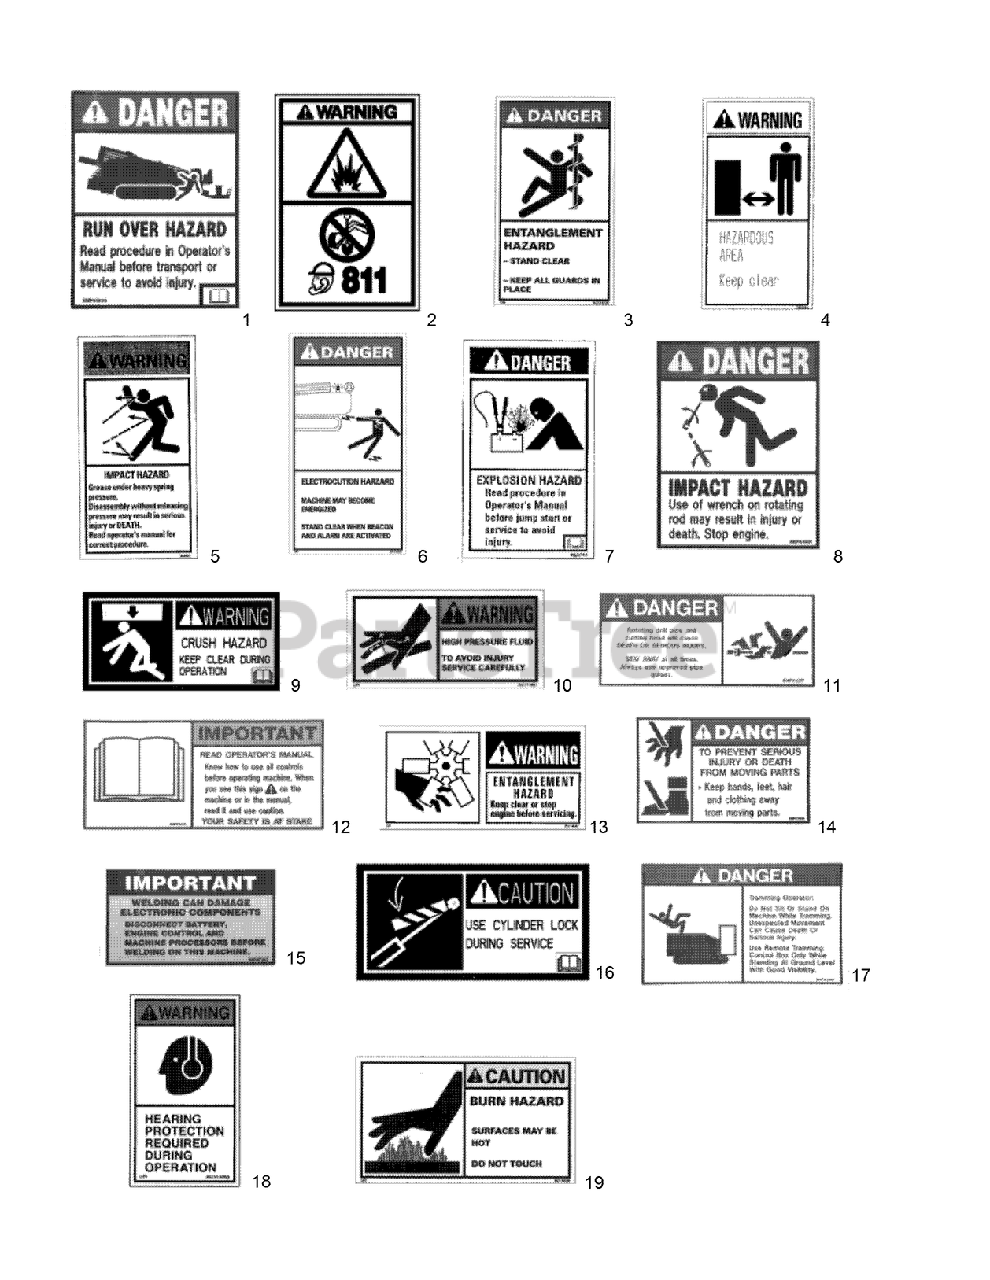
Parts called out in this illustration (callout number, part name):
1	DECAL - Danger, Run Over Hazard
2	DECAL-Warning, Call Before Digging
3	DECAL - Danger, Entanglement Hazard
4	DECAL - Warning, Hazardous Area
5	DECAL - Warning, Grease Under Pressure
6	DECAL - Danger, Electrocution
7	DECAL - Danger, Explosion Hazard
8	DECAL - Danger, Impact Hazard
9	DECAL - Warning, Crush Hazard
10	DECAL - Danger, Hydraulic Components Contain High Pressure Fluid
11	DECAL - Danger, Rotating Drill and Cutting Head
12	DECAL - Important, Read Operators Manual
13	DECAL - Warning, Fan
14	DECAL - Danger, Moving Parts - Keep Hands and Feet Away
15	DECAL - Important, Welding Can Damage Electronic Components
16	DECAL - Caution, Cylinder Lock
17	DECAL - Danger, Tramming Operation
18	DECAL - Warning, Hearing Protection Required
19	DECAL - Caution, Burn Hazard
